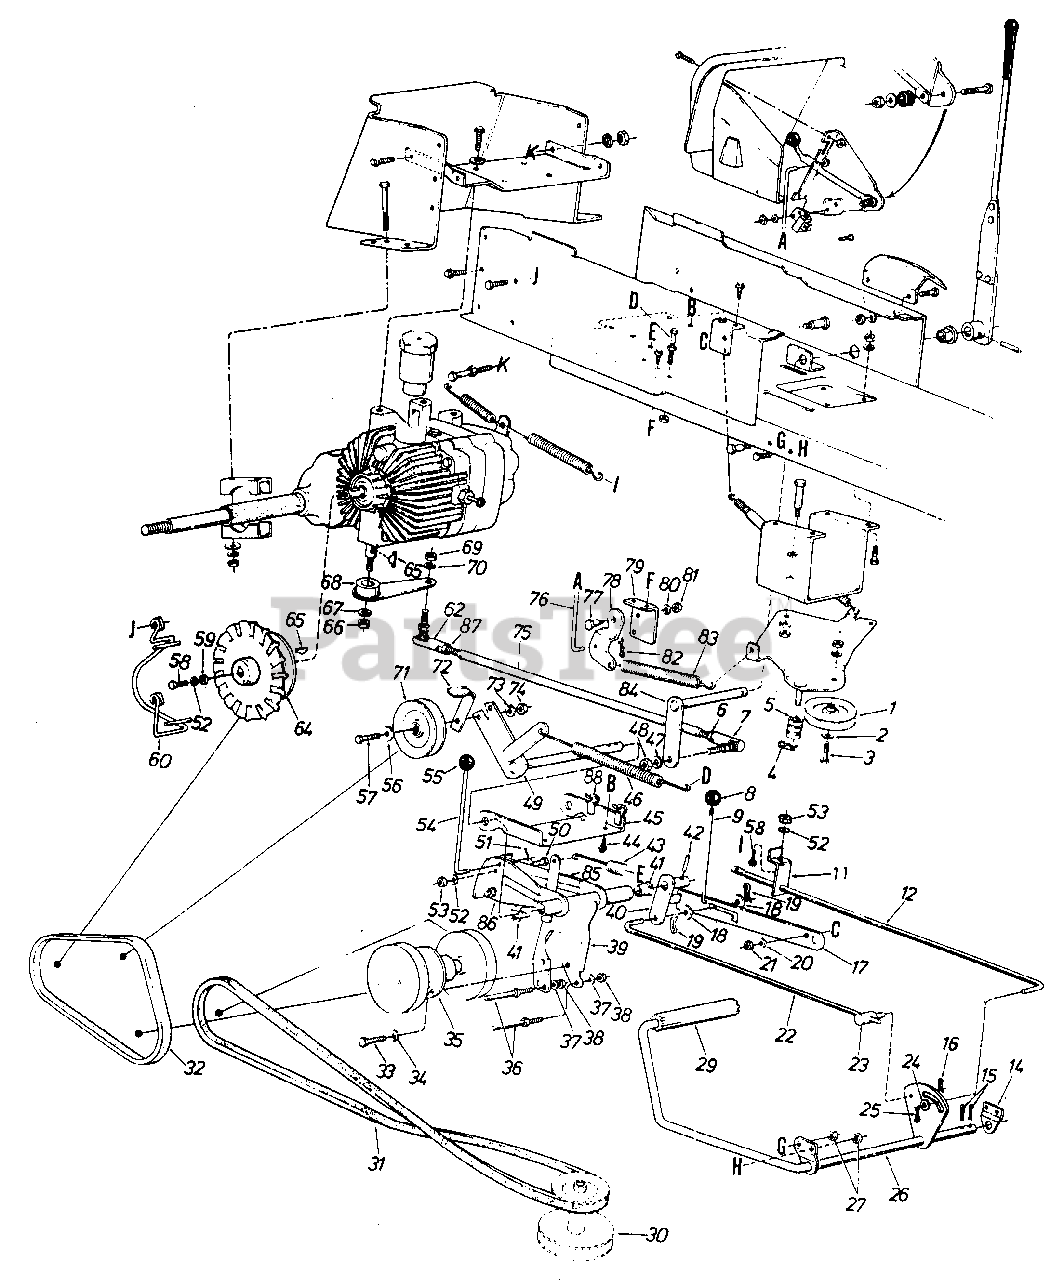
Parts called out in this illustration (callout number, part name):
1	4" Dia. "V"-ldler Pulley
2	Fl-Wash. 3/8" I.D.
3	Hex Bolt 3/8-16 x 1.25" Lg.
4	Intern. Cotter Pin 5116" Dia.
5	Spacer
6	Hex Jam L-Nut 3/8-24 Thd.
7	Ball Joint Ass'y. 3/8-24 Thd.
9	Parking Brake Link
11	Brake Rod Hanger
14	Clutch Rod Brg. Brkt.
15	Cotter Pin 118" Dia. x 1.00" Lg.
16	Hairpin Cotter 1/2" Dia.
17	Parking Brake Cam
18	Fl-Wash. .406 I.D. x 1.00" O.D. x .030
19	Hairpin Cotter 1/2" Dia.
20	L-Wash. 5/16" I.D.
21	Hex Nut 5/16-18 Thd.*
22	Brake Cam Rod
23	Pivot Bushing
24	Fl-Wash. .401" I.D. x .749" O.D. x .057" Thk.
25	Cotter Pin 3132" Dia. x .75" Lg.
26	Clutch Brake Pedal Ass'y.
27	Hex L-Nut 3/8-16 Thd.
29	Foot Pad
30	Two-Step Engine Pulley 4.75" and 5.56"
31	"V"-Belt 1/2" X 59" Lg.
32	"V"-Belt 1/2" X 37" Lg.
33	Hex Sems Bolt 5/16-18 x .75" Lg.
34	L-Wash. 5/16" I.D.
35	Jack Shaft Ass'y.
36	Stud 3/8-16 x 3.62" Lg.
37	L-Wash. 3/8" I.D.
38	Hex Nut 3/8-16 Thd.
39	Jack Shaft Mtg. Brkt. Ass'y.
40	Clutch Idler Horn Ass'y.
41	Nyliner 5/8" I.D. x .88" Lg.
42	Spring Pin Spiral 1/4" Dia. x 1.5" Lg.
43	Ext. Spring
44	Hex Wash. Hd. Self-Tap Scr. 1/4-20 X .50" Lg.
45	Idler Mtg. Brkt.
46	Ext. Spring
47	L-Wash. 3/8" I.D.*
48	Hex Nut 3/8-24 Thd.
49	Clutch Brkt. Ass'y.
50	Hex Bolt 1/4-20 x .50" Lg.
51	Internal Cotter Pin 5/16" Dia. Rod
52	L-Wash. 1/4" I.D.
53	Hex Nut 1/4-20 Thd.*
54	Relief Valve Lockout Rod
56	Fl-Wash. 3/8" I.D.
57	Hex Bolt 3/8-16 x 1.25" Lg.
58	Hex Bolt 1/4-20 X .62" Lg.
60	Belt Guard Ass'y.
62	Ball Joint Ass'y. 3/8-24 L.H. Thd.
64	Transaxle Pulley w/ Fan
65	Hi-Pro Key 118" x 1/2" Dia.
66	Hex Nut 3/8-16 Thd.
67	L-Wash. 3/8" I.D.*
68	Pintle Arm Ass'y.
69	Hex Nut 3/8-24 Thd.
70	L-Wash. 3/8" I.D.
71	4" "V"-ldler Pulley
74	Hex Nut 3/8-16 Thd.
75	Speed Control Rod
76	Deck Control Rod
77	Shld. Scr. .437" Dia. x .162" Lg. (5/16-18)
78	Deck Control Pivot Brkt.
79	Parking Brake Cam Mtg. Brkt.
80	L-Wash. 5/16" I.D.*
81	Hex Nut 5/16-18 Thd.
82	Internal Cotter Pin 5/16" Rod
83	Extension Spring
84	Speed Control Shaft Ass'y.
85	Relief Valve Cam L.H.
86	Relief Valve Cam R.H.
87	Hex Jam L-Nut 3/8-24 L.H. Thd.
88	Plastic Hose Clamp
